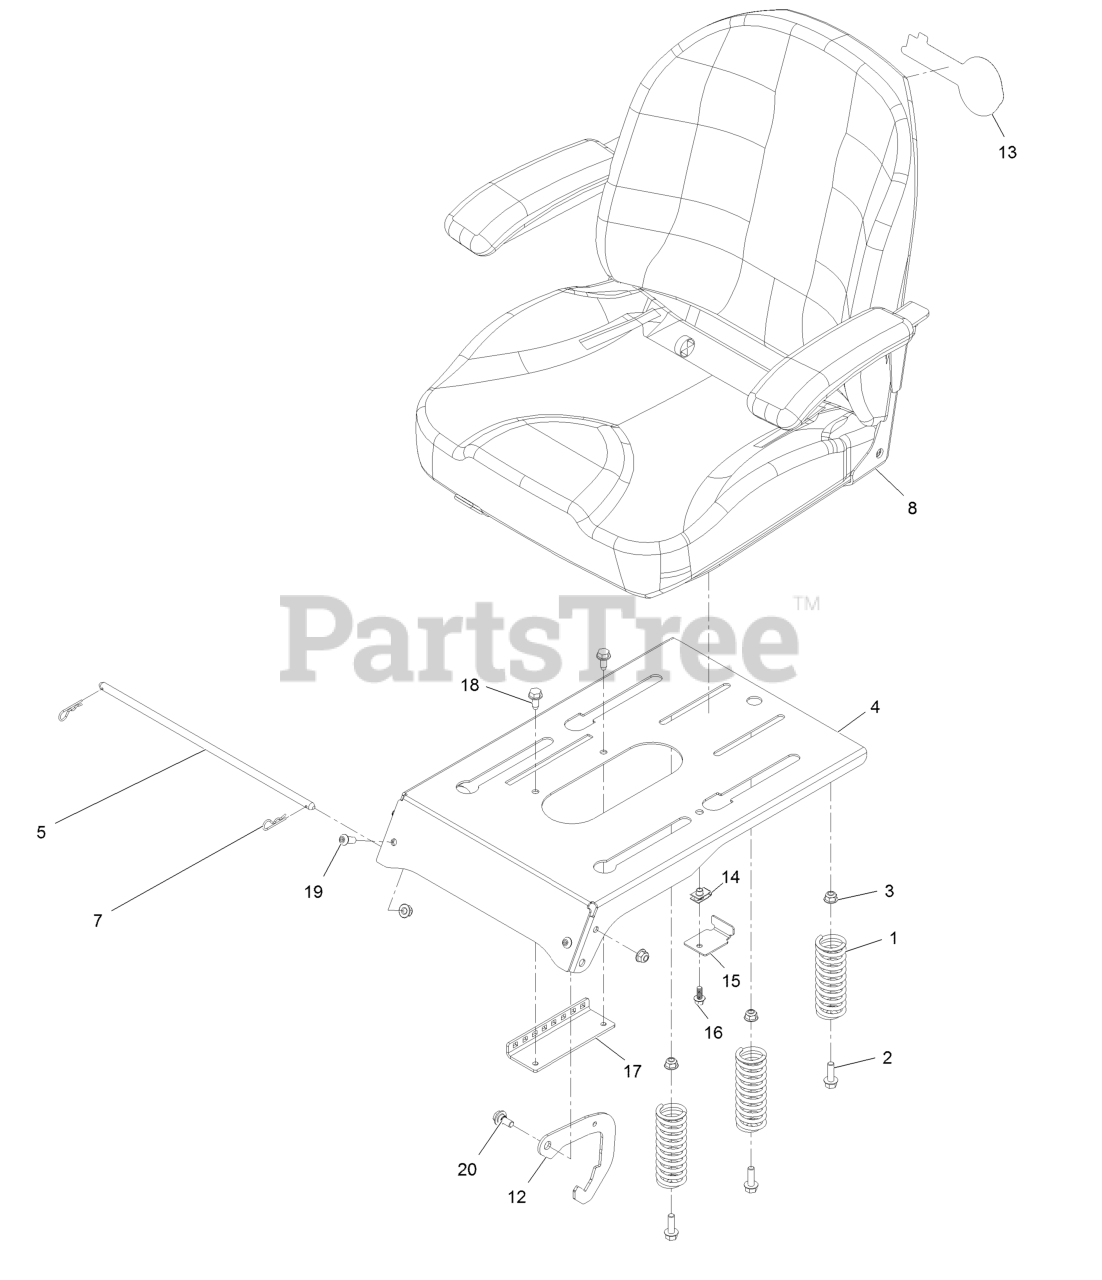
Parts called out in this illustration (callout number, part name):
1	SPRING-COMPRESSION
2	SCREW-HHF
3	NUT-HF, NI
4	PAN-SEAT, DELUXE
5	ROD-PIVOT, NARROW
7	PIN-COTTER
8	SEAT ASM, EXMARK
12	LATCH-SEAT
13	DECAL-EXMARK LOGO
14	Nut-Retainer-Panel 1/4-20
15	BRACKET-STOP, SEAT
16	SCREW-HHF
17	BRACKET-LATCH, SEAT
18	Screw-HWH 5/16-18 X 3/4 Tf
19	SCREW-HSBH
20	SCREW-SHOULDER
